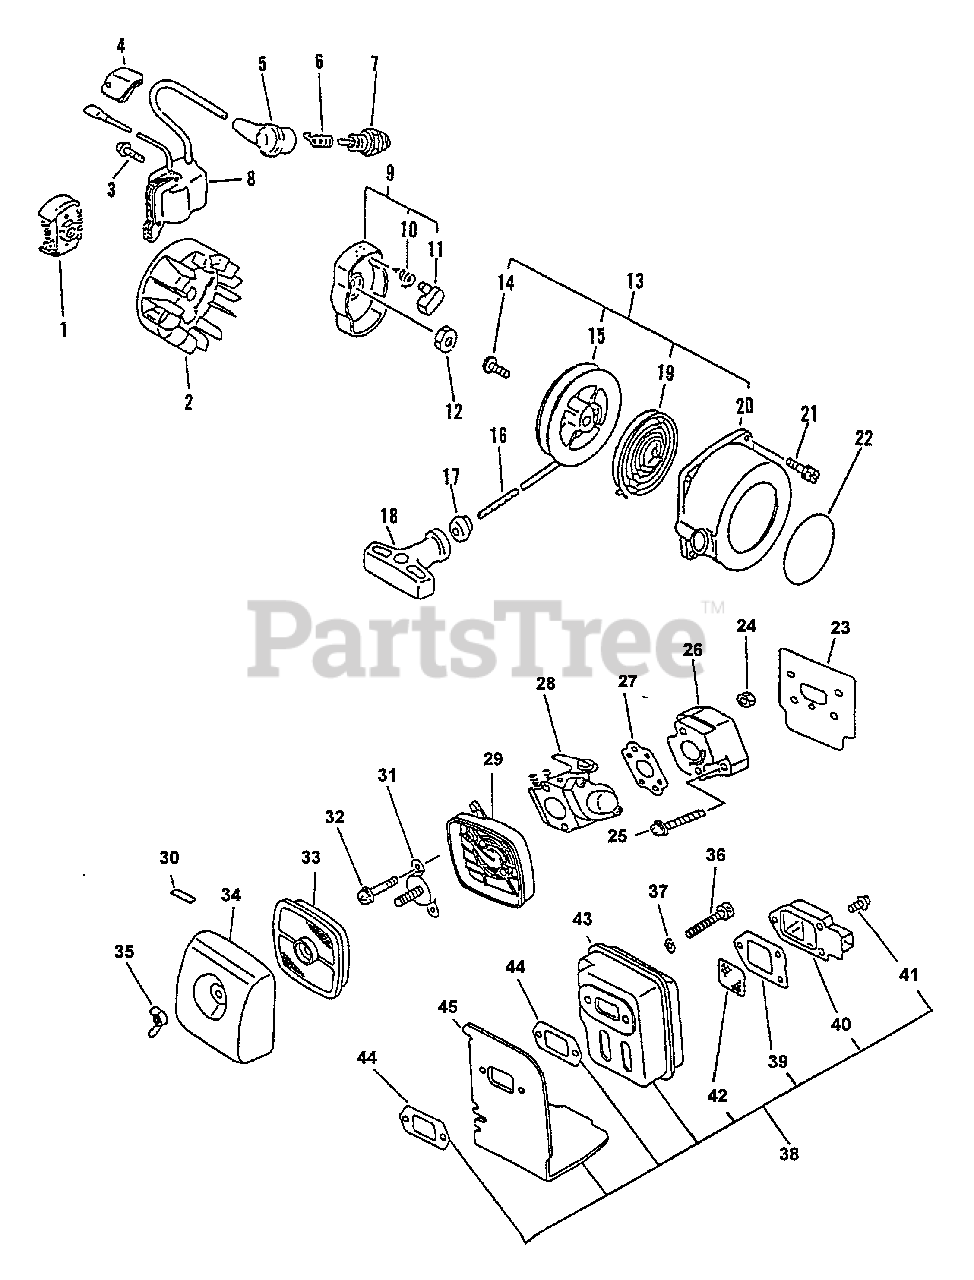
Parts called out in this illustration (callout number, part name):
1	CLUTCH ASSY
2	FLYWHEEL
3	SCREW - 4X20
4	COVER, DUST
5	CAP, SPARK PLUG
6	TERMINAL, SPARK PLUG CAP
7	SPARK PLUG
8	COIL, IGNITION
9	STARTER PAWL ASSY
10	SPRING, RETURN
11	PAWL, STARTER - BLACK
13	STARTER ASSY
15	REEL, ROPE
16	ROPE, STARTER - 3X990
17	GUIDE, ROPE
18	GRIP, STARTER
19	SPRING, REWIND
20	CASE, STARTER
21	LABEL - ECHO
22	SCREW - 4X16
23	SHIELD, INTAKE
25	SCREW - 5X20
26	INSULATOR, INTAKE
27	GASKET, INTAKE
28	CARBURETOR C1U-K34
29	AIR FILTER CASE ASSY
30	LABEL - CHOKE
31	PLATE, PREVENT
32	SCREW - 5X65
33	FILTER, AIR - SINGLE LAYER
34	COVER, AIR FILTER
35	WINGNUT - 6
36	SCREW - 5X55
37	WASHER - 5
38	MUFFLER ASSY
39	GASKET, EXHAUST
40	GUIDE, EXHAUST - OUTER
41	SCREW - 4X10
42	SCREEN, SPARK ARRESTOR
43	MUFFLER ASSY
44	GASKET, EXHAUST
45	COVER, EXHAUST
